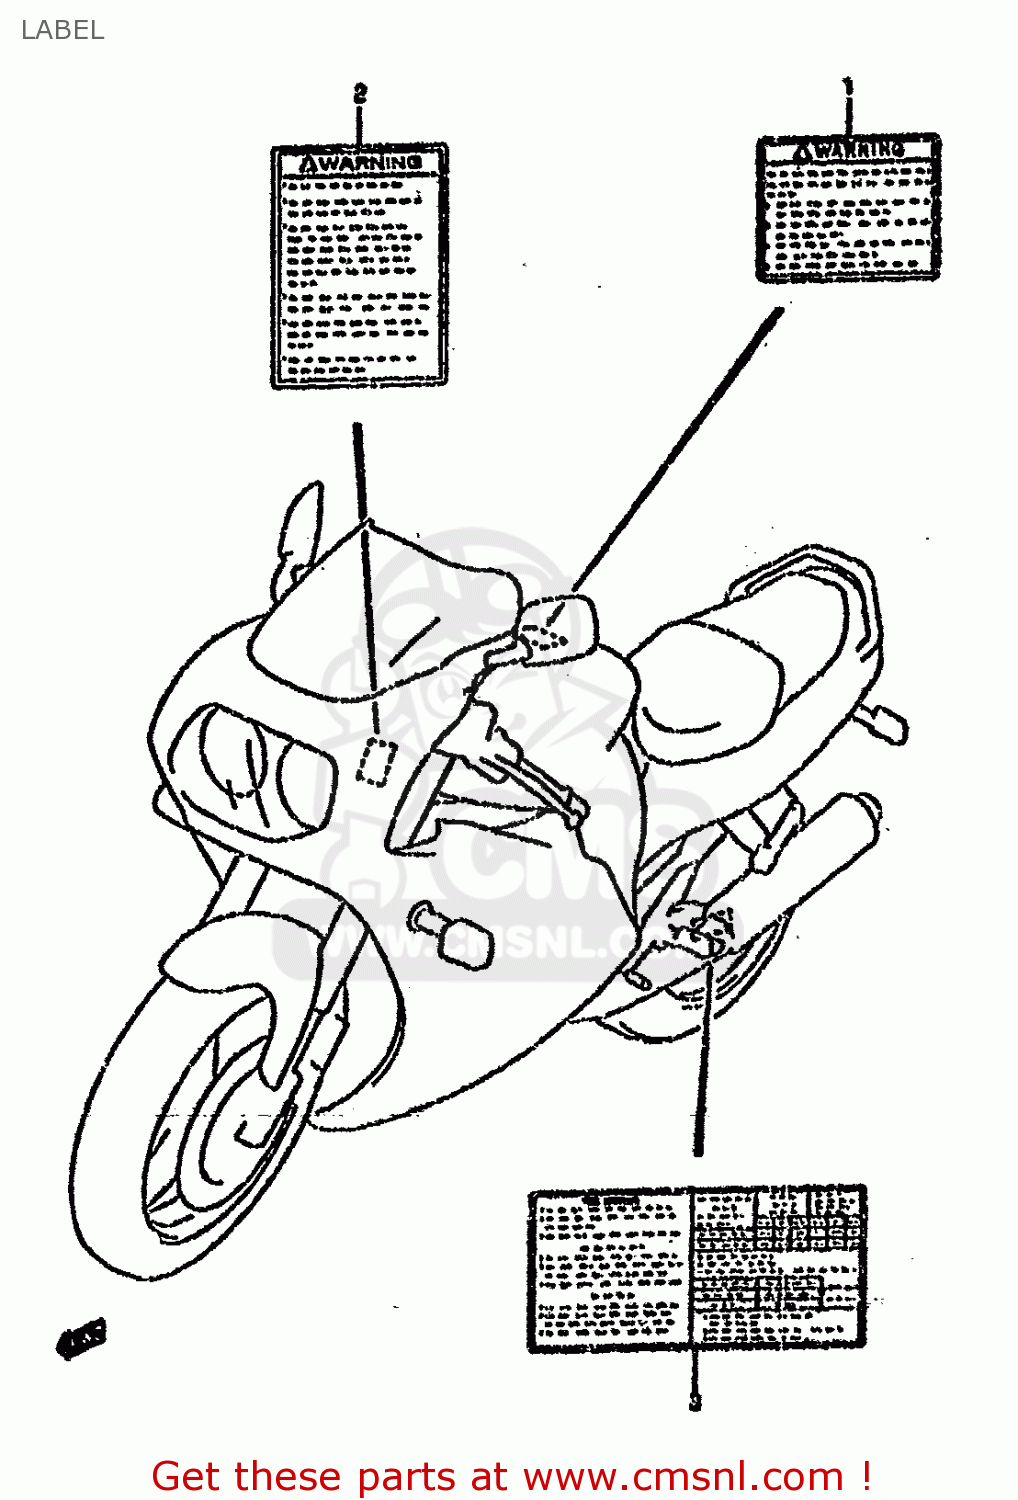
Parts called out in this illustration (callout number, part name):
1	LABEL, WARNING SAFETY
2	LABEL (WARNING SCREEN)
3	LABEL (TIRE INFORMATION)
